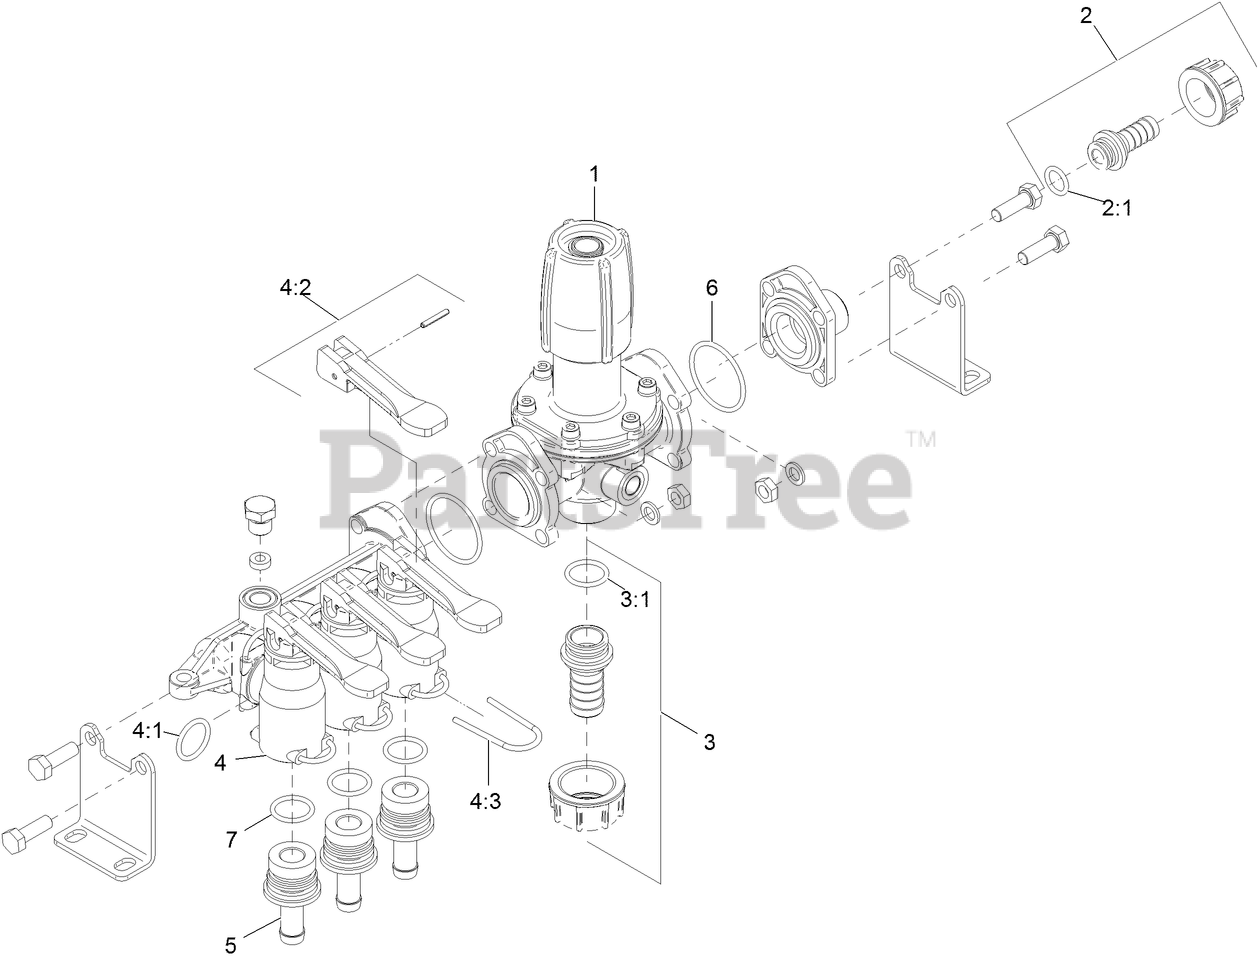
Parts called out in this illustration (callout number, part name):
1	REGULATOR
2	FLYNUT ASSEMBLY
2:1	O-RING KIT, REGULATOR INLET BARB
3	FLYNUT ASSEMBLY
3:1	O-RING KIT, REGULATOR OUTLET BARB
4	VALVE ASSEMBLY W/ O-RING
4:1	O-RING KIT, VALVE INLET
4:2	LEVER AND PIN ASSEMBLY
4:3	WIREFORM RETAINER KIT
5	HOSE BARB
6	O-RING KIT, REGULATOR FLANGE
7	O-RING KIT, VALVE OUTLET BARB
